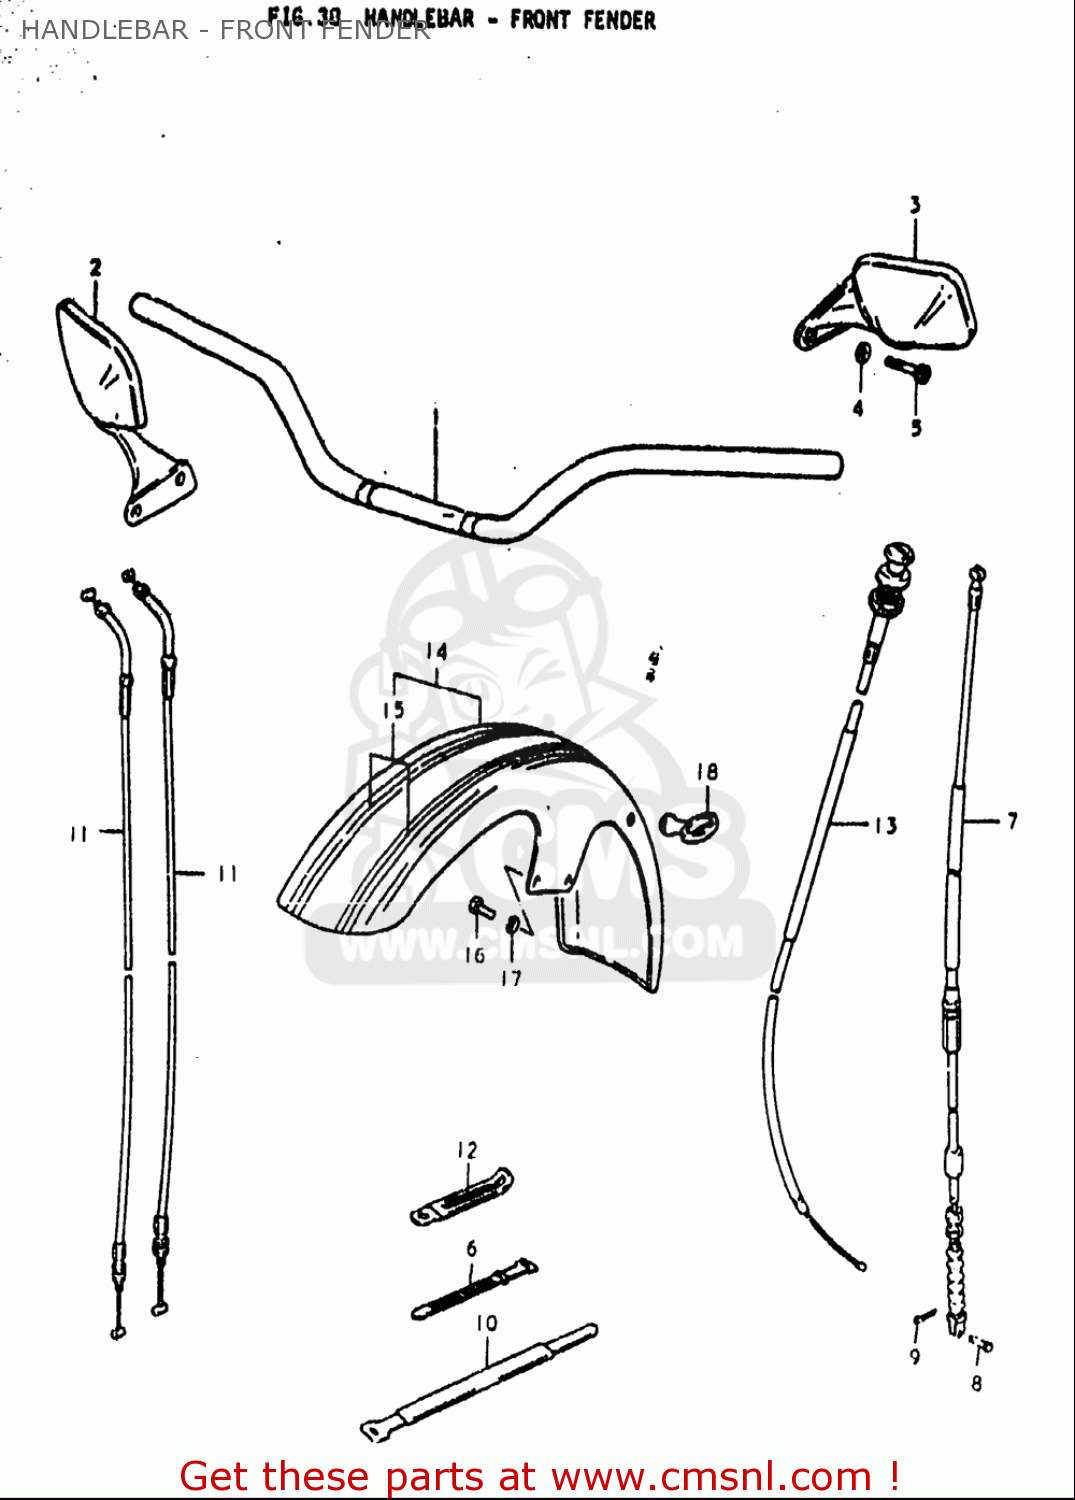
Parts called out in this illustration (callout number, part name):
1	HANDLEBAR
2	MIRROR ASSEMBLY,RIGHT
3	MIRROR ASSEMBLY,LEFT
5	BOLT
6	CLAMP(L:120)
7	CABLE,CLUTCH
8	PIN(L:15)
9	PIN
10	CLAMP
11	CABLE ASSY,THROTTLE
12	CLAMP(L:65)
13	CABLE ASSY,STARTER
14	FENDER,FRONT
16	BOLT
17	WASHER,LOCK
18	GUIDE,CABLE
